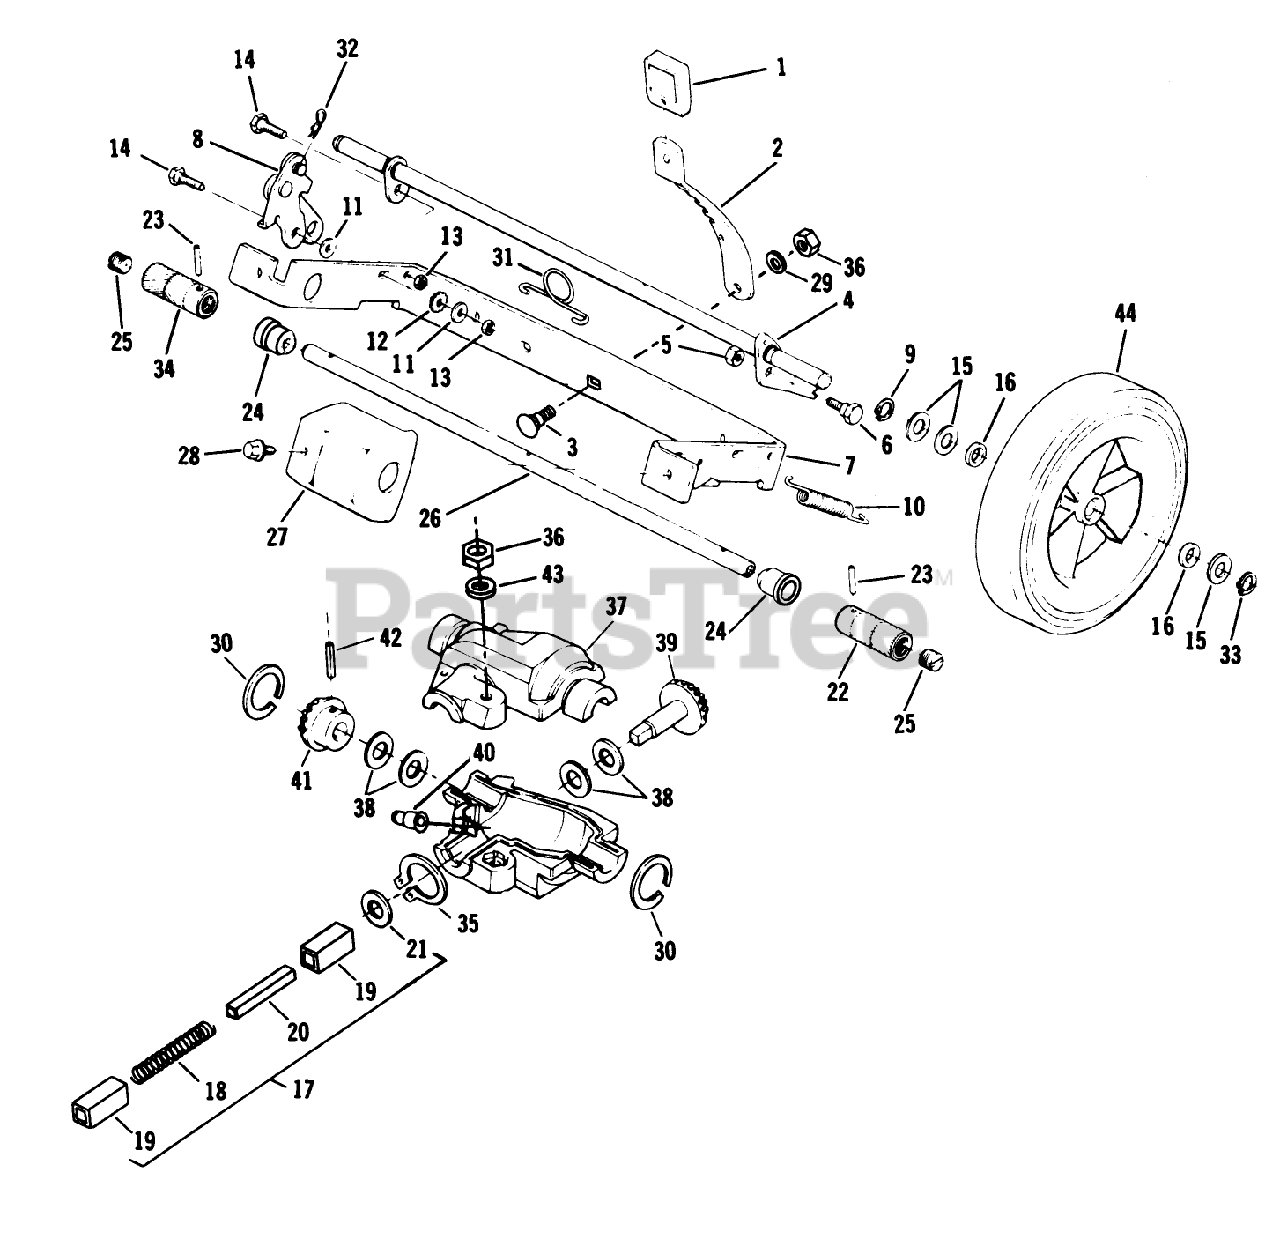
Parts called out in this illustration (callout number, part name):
1	KNOB
2	LEVER
5	LOCKNUT E
6	BOLT RB&W
7	BRACKET *GREEN
9	RET RING
10	SPRING
11	WASHER S
13	STOP NUT
14	BOLT RB&W
15	SPACER
16	WASHER
18	SPRING
19	BUSHING BKWY
21	THRUST WASHER
22	ROLLER (LEFT) VS
22	ROLLER-LH
23	PIN
24	SLEEVE &BEARING AY
25	GREASE PLUG
26	DRIVE SHFT TAG AY
27	GUARD
29	WASHER S
31	SPRING N.A.S
33	RET RING
34	ROLLER (RIGHT) VS
34	ROLLER-RH
36	LOCKNUT E
37	GEARCASE AY-SERV
38	THRUST WASHER
39	GEAR BEST
40	ZERK FITTING
41	GEAR ADVANCE
42	ROLL PIN
43	WASHER F
44	WHEEL & TIRE KIT
